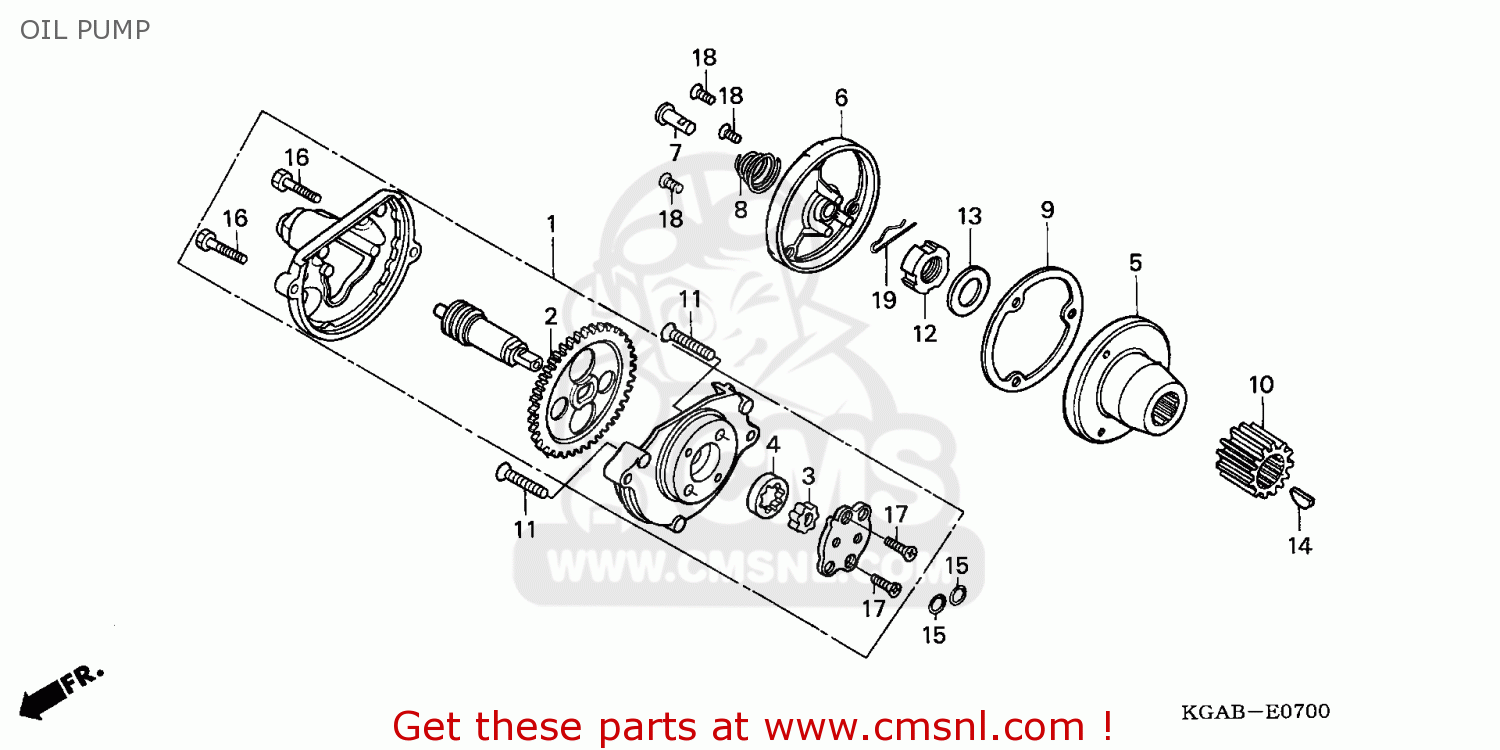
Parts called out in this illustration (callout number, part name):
1	OIL PUMP ASSY.
2	GEAR,OIL PUMP DRI
3	INNER ROTOR,OIL P
4	OUTER ROTOR,OIL P
5	ROTOR COMP,OIL FI
6	CAP OIL FILTER RO
7	OIL THROUGH
8	SPRING,OIL THROUG
9	GASKET,OIL FILTER (NAS)
10	GEAR A,PRIMARY DR
11	SCREW,FLAT,6X30
12	NUT LOCK,16MM
13	WASHER,16MM
14	KEY,WOODRUFF,25X1
15	O RING 9.4X2.4
16	BOLT,HEX,5X20
17	SCREW,FLAT 4X12
18	SCREW,OVAL,5X12
19	PIN,LOCK,8MM
